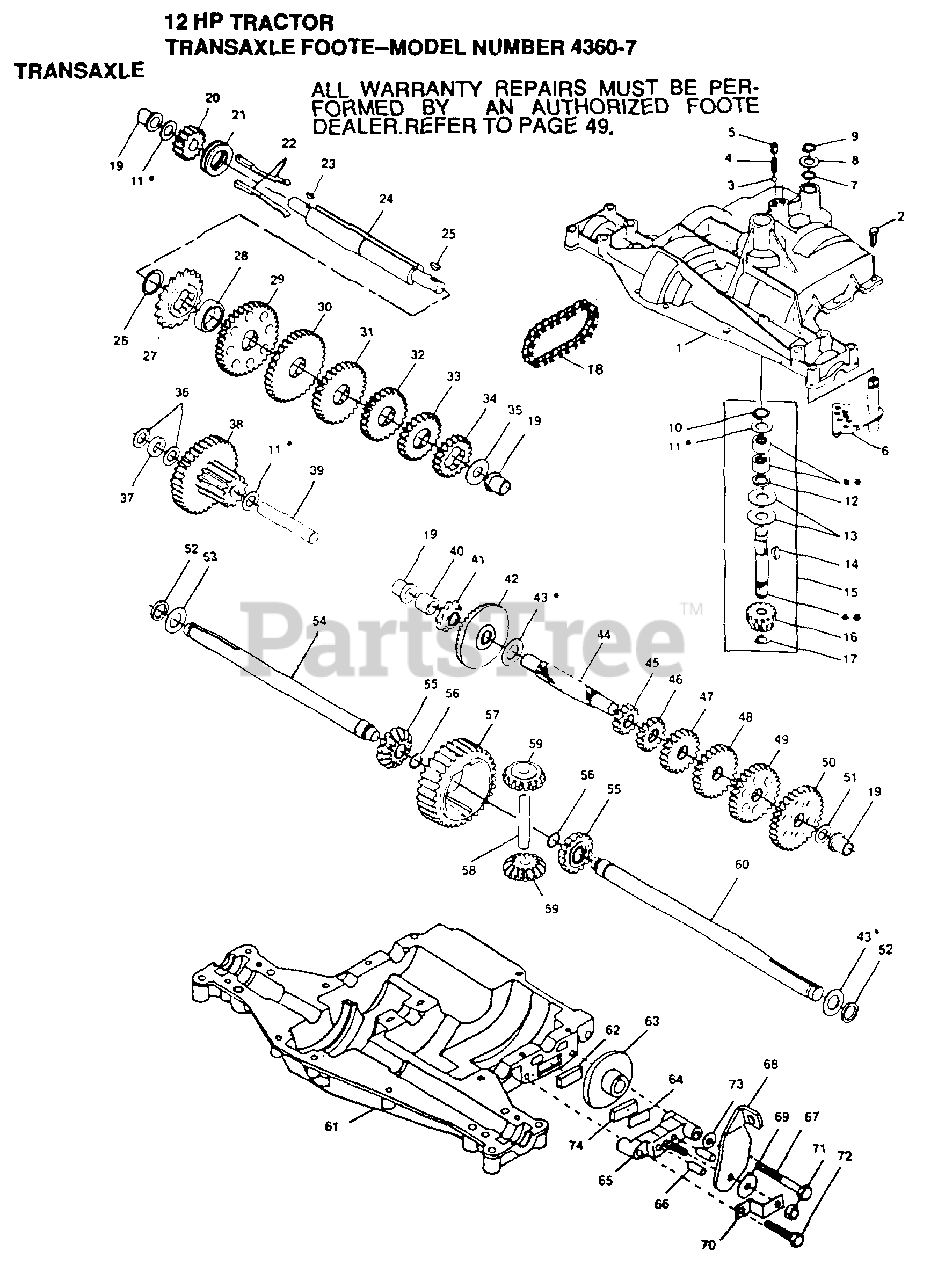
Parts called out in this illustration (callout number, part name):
3	BALL DETENT
4	SPRING, DETENT
5	SCREW, SET
6	ASSY SHIFTER
8	WASHER PLAIN
8A	WASHER PLAIN
8B	WASHER PLAIN
8C	WASHER PLAIN
8D	WASHER PLAIN
8E	WASHER PLAIN
8F	WASHER PLAIN
9	RING RETAINING
10	RING RETAINING
11	WASHER PLAIN
11A	WASHER PLAIN
11B	WASHER, PLAIN .632 X 1.00 X .026
11C	WASHER PLAIN
11D	WASHER PLAIN
11E	WASHER PLAIN
11F	WASHER PLAIN
11G	WASHER PLAIN
11H	WASHER, PLAIN .632 X 1.00 X .060
11I	WASHER PLAIN
13	WASHER, PLAIN .632 X 1.38 X .046
14	KEY WOODRUFF #9
15	ASSY KIT INPUT SHAFT
16	PINION, BEVEL, 14 TEETH
17	RING, RETAINING
18	CHAIN, 24 PITCHES
19	BEARING, FLANGE
20	GEAR SPUR, 14 TEETH
21	COLLAR CLUTCH
22	KEY CLUTCH
23	KEY WOODRUFF #3
24	SHAFT INTERMEDIATE
25	KEY, WOODRUFF, #61
26	RING, RETAINING
27	SPROCKET, 18 TEETH
29	GEAR, SPUR, 37 TEETH
30	GEAR, SPUR, 35 TEETH
31	GEAR, SPUR, 30 TEETH
32	GEAR, SPUR, 25 TEETH
33	GEAR, SPUR, 22 TEETH
35	WASHER, PLAIN .640 X 1.37 X .061
36	WASHER, PLAIN .632 X 1.00 X .026
37	SPACER .630 X 1.00 X .169
38	ASSY GEAR COMB 12&35 TEETH
39	SHAFT IDLER
40	SPACER .635 X .875 X .755
41	SPROCKET, 9 TEETH
42	GEAR, BEVEL, 42 TEETH
43	WASHER PLAIN
43A	WASHER PLAIN
43B	WASHER PLAIN
43C	WASHER PLAIN
43D	WASHER PLAIN
43E	WASHER PLAIN
43F	WASHER, PLAIN .758 X 1.25 X .031
43G	WASHER PLAIN
43H	WASHER PLAIN
43I	WASHER PLAIN
43J	WASHER PLAIN
43K	WASHER PLAIN
43L	WASHER PLAIN
44	SHAFT, DRIVE
45	GEAR, SPUR, 12 TEETH
46	GEAR SPUR, 15 TEETH
47	GEAR, SPUR, 20 TEETH
48	GEAR, SPUR, 25 TEETH
49	GEAR, SPUR, 28 TEETH
50	GEAR, SPUR, 31 TEETH
51	WASHER, PLAIN .632 X 1.00 X .060
53	WASHER PLAIN
54	AXLE LEFT HAND
55	GEAR, MITER, 15 TEETH
56	RING, RETAINING
57	GEAR, SPUR, 32 TEETH
58	SHAFT, CROSS
59	GEAR, MITER, 15 TEETH
60	AXLE, R.H.
61	HOUSING LOWER
62	PUCK, FRICTION
63	DISC, BRAKE
65	JAW, BRAKE
66	PIN, DOWEL
67	SCREW TAPPING
68	LEVER, ACTUATING
69	WASHER, PLAIN .321 X 1.00 X .055
70	BRACKET, ANTI-ROTATION
71	LOCKNUT 5/16-24
72	SCREW TAPPING
73	WASHER PLAIN
74	PUCK, FRICTION
